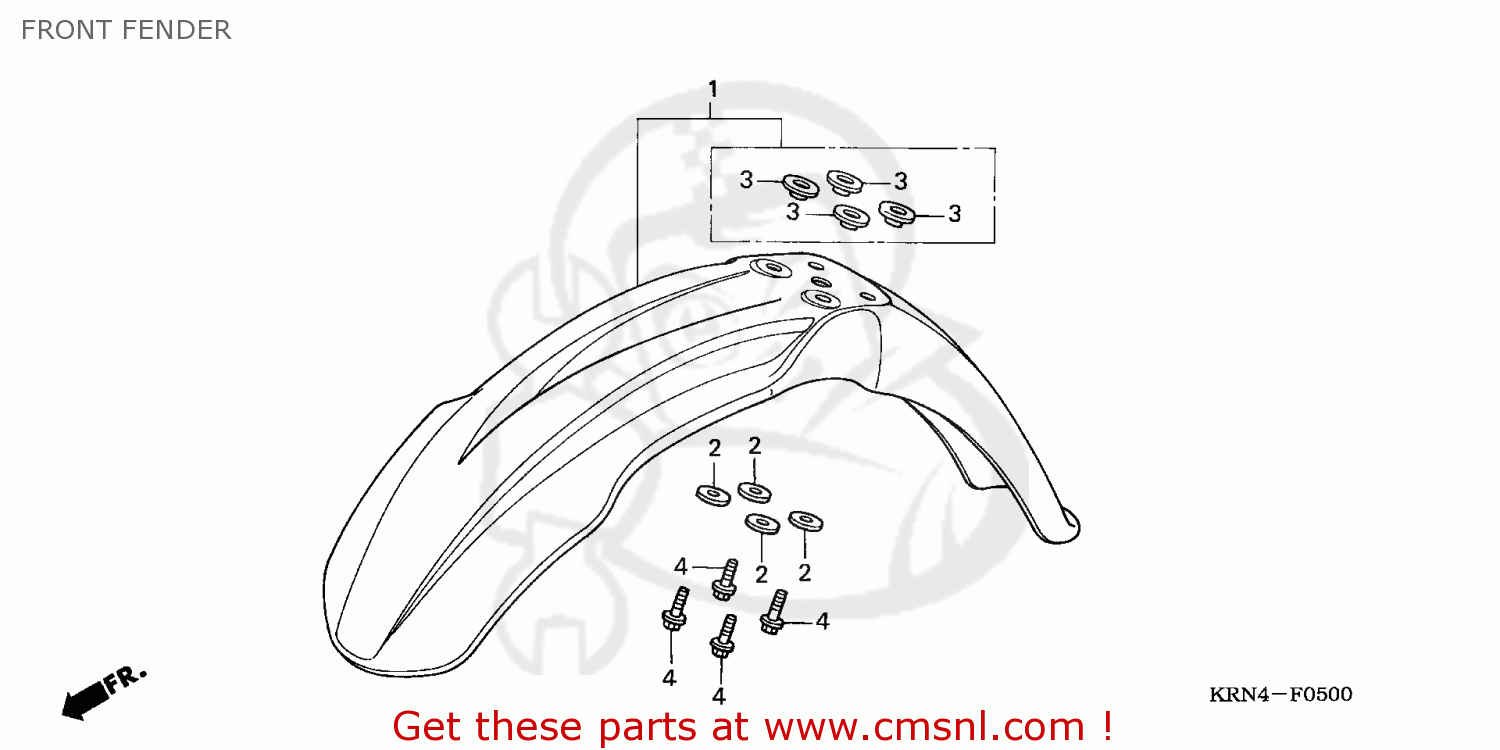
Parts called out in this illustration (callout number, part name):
1	SUB ASSY FENDER F
2	WASHER,FENDER MT.
3	COLLAR FR FENDER
4	BOLT,FLANGE,SH,6X16
